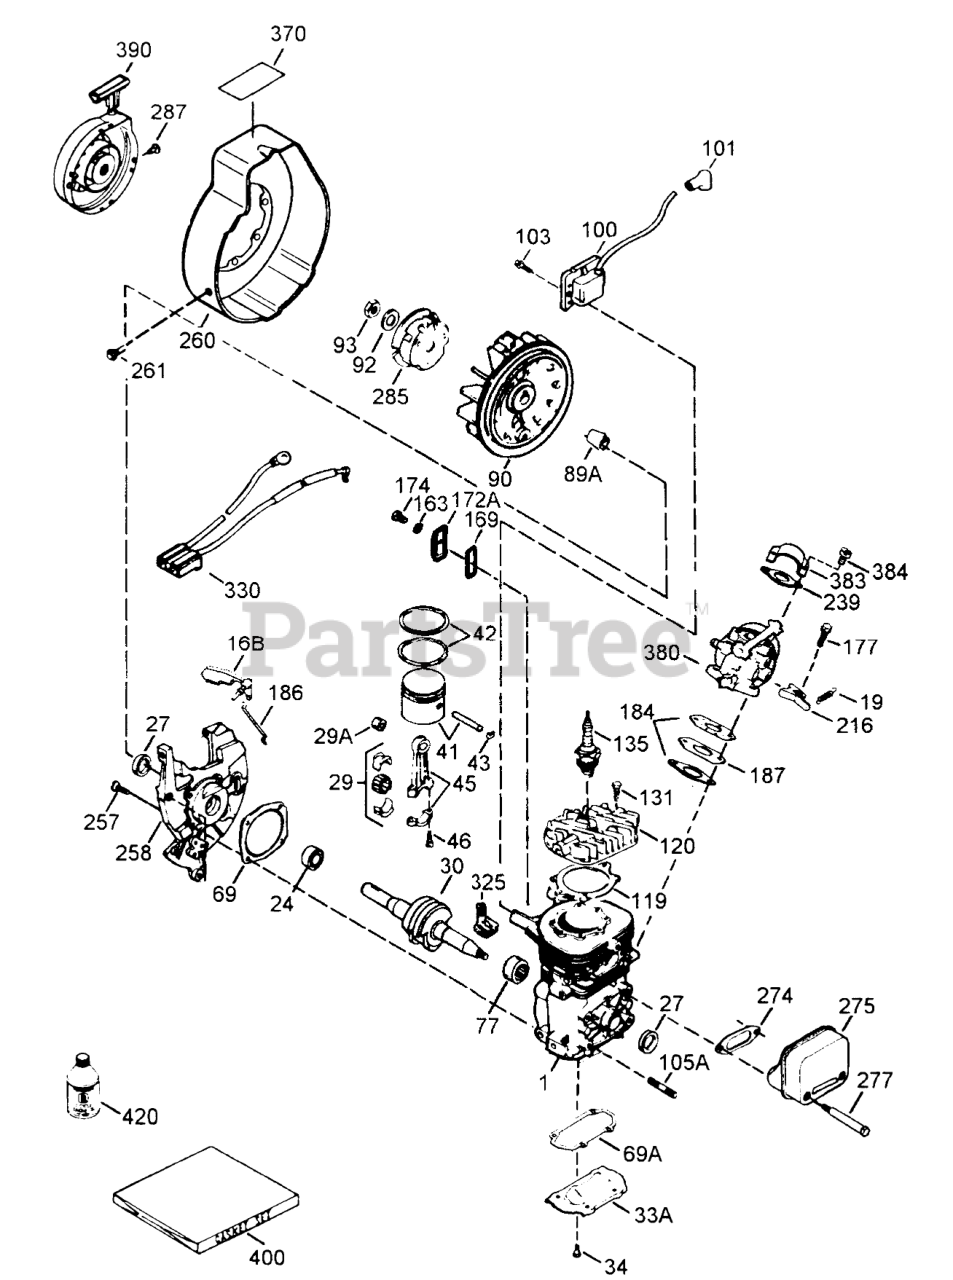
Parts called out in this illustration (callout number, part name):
1	Block Ass-y-Cylinder (Order short block if replacement is required)
16B	Vane-Air
19	Spring-Extention
24	Bearing-Ball
27	Seal-Oil
29	Needle Bearing and Liner Set (37 Needles)
29A	Bearing-Cartridge
30	Crankshaft
33A	Plate-Cover
34	Screw (T-25, 10-24 x 1/2)
41	Piston & Pin Ass-y (Incl. Ref. #43)
42	Ring Set
43	Ring-Retaning
45	Rod Ass-y-Connecting (Incl. Ref. #29, 29A & 46)
46	Bolt-Rod, Connecting
69	Gasket-Cover, Cylinder
69A	Gasket-Plate, Cover
77	Bearing-Cartridge
89A	Blade (20 inch)
90	Flywheel
92	Washer-Belleville
93	Nut-Flywheel
100	Solid State Assembly (Incl. Ref. #101)
101	Cover-Spark Plug
103	Screw
119	Gasket-Head, Cylinder
120	Head-Cylinder
131	Screw (T-30, 1/4-20 x 3/4)
135	Spark Plug-Resistor (R C J 8Y)
169	Cover-Compression, Release
172A	Cover-Release, Compression
174	Screw (T-25, 10-24 x 1/2)
177	Screw (5/32 Allen, 1/4-20 x 1)
184	Gasket-Carburetor
186	Governor-Link
216	Lever-Adjusting, Rpm
239	Gasket-Cleaner, Air
257	Screw (T-30, 1/4-20 x 5/8)
258	Base Ass-y-Blower Housing (Incl Ref. #27)
260	Housing-Blower
261	Screw (1/4-20 x 1/2)
274	Gasket-Exhaust
275	Muffler
277	Screw (1/4-20 x 2-3/4)
285	Cup-Starter
287	Rivet-Pop
325	Clip-Wire
330	Harness-Wire
370	Decal-Warning
380	Carburetor (Incl. Ref. #184)
383	Baffle-Carburetor
390	Starter-Rewind
400	Gasket Set
422	2-Cycle Oil (8oz)
